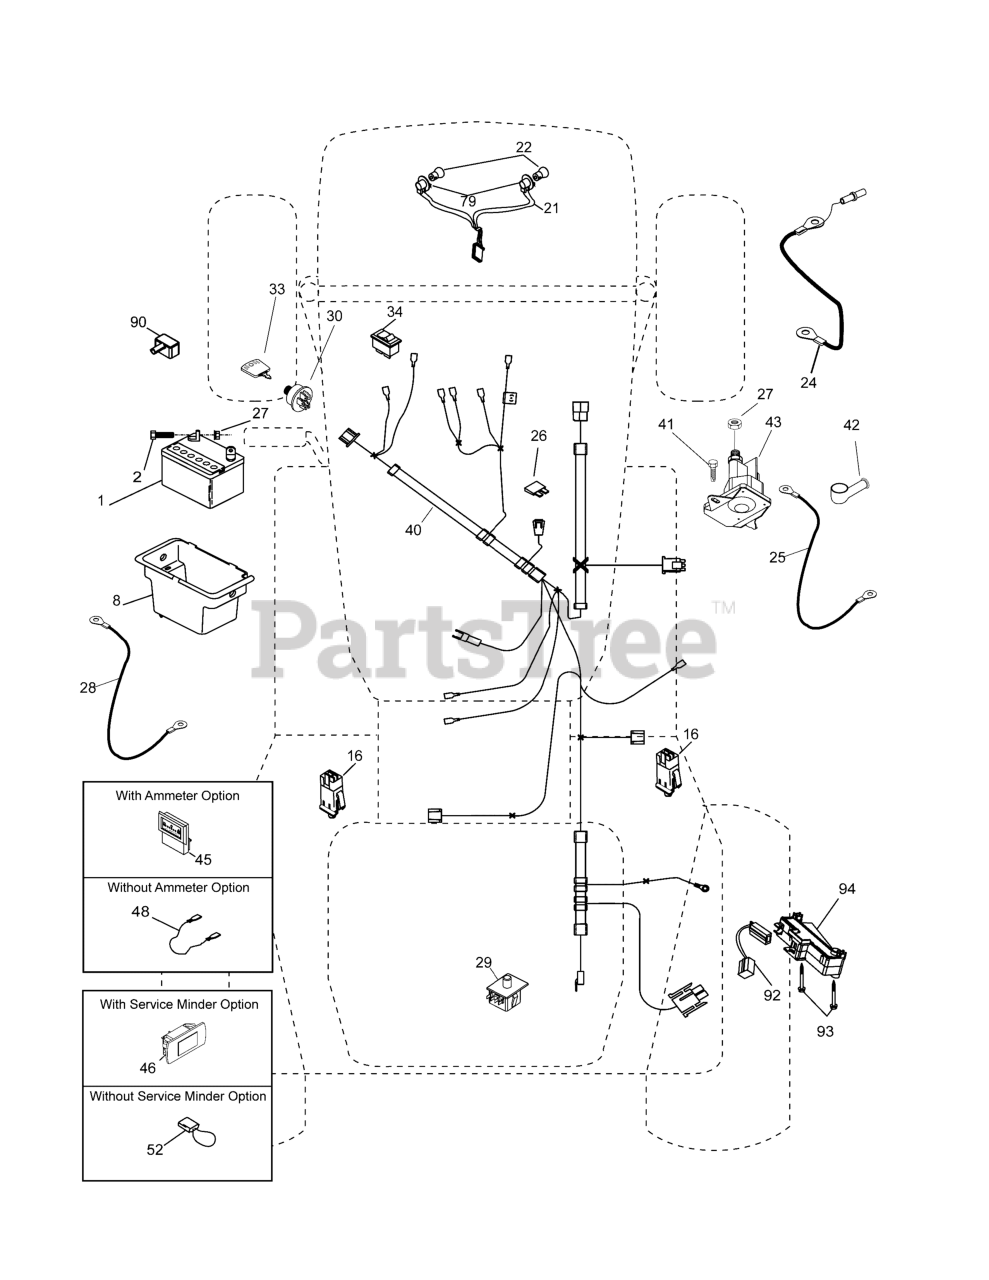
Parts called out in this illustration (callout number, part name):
1	Battery
2	Bolt Hex Hd 1/4-20 unc x 3/4
8	Box Battery
16	Switch Interlock
21	Harness Asm Light w/4152j
22	Bulb Light #1156
24	Cable Battery 6 Ga. 11" Red
25	Cable Battery
26	Fuse 20 AMP
27	Nut Keps Hex 1/4-20 unc
28	Cable Ground 6 Ga. 12" Black
29	Switch Seat
30	Switch Ign
33	Key/Chain
34	Switch Light/Reset
40	Harness Ign
41	Bolt Blk Fin Hex 1/4-20
42	Cover Terminal Red
43	Solenoid
79	Socket Asm. Bulb Twistlock
90	Cover Terminal Battery
92	Harness Pigtail
93	Screw Plastite 10-14 x 2.0
94	Module Reverse ROS
